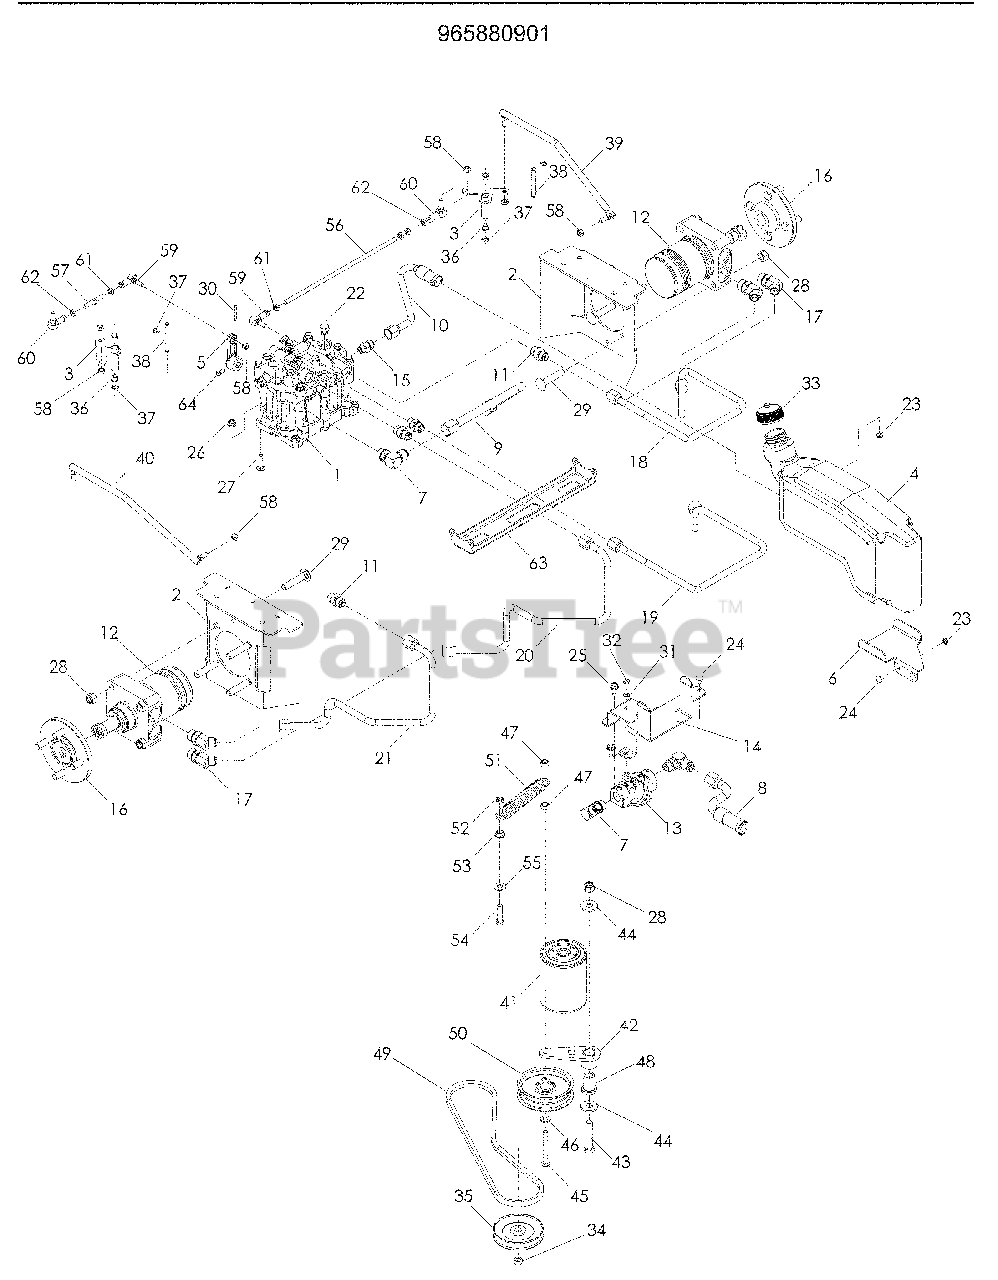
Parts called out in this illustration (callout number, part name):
1	PUMP, DUP10S
2	MOUNT, WHEEL MOTOR
3	BELLCRANK, MOTION
4	RESERVOIR, HYDRAULIC
6	SUPPORT, RESERVOIR FT
8	LINE, HYD, SUCTION
9	LINE, HYD, CHARGE
10	LINE, HYD, CASE
11	CONNECTOR, STRAIGHT
13	FILTER HEAD
14	SUPPORT, RESERVOIR RR
15	FITTING, HYD
16	HUB, WHEEL
17	ELBOW 45O
18	LINE, HYD, D
19	LINE, HYD, C
20	LINE, HYD, B
21	LINE, HYD, A
22	PLUG, 6408-6
23	NUT ¼-20 HEX THIN NYLOC
24	RHSSNB ¼-20 x ½
25	BOLT 5/16-18 x ¾ THD FRM
26	NUT 5/16-18 FLANGE NYLOC
27	RHSNB 5/16-18 x 1¼
28	NUT ½-13 HEX NYLOC
29	RHSNB ½-13 x 2½
30	PIN, SPIRAL 5/32 x 1½
31	WASHER ¼ SLW
32	HCS ¼-20 x 5/8
34	NUT, M10-1.5 L/H HEX
35	PULLEY, PUMP
36	BUSHING, BAIL 5/16
37	RING RETAINING 5/16 EXT
38	PIN, MOTION
39	LINKAGE, CONTROL LT
40	LINKAGE, CONTROL RT
41	FILTER, OIL
42	IDLER ARM WLDMT
43	HCS ½-13 x 2½
44	WASHER ½ FLAT
45	HCS 3/8-16 x 3 TAPBOLT
46	WASHER, 3/8 SAE FLAT
47	NUT 3/8-16 HEX NYLOC
48	PIVOT, IDLER
50	PULLEY, IDLER
51	SPRING, TRACTION
52	NUT 3/8-16 HEX JAM NYLOC
53	NUT 3/8-16 HEX WHIZLK
54	HCS 3/8-16 x 1½ TAPBOLT
55	WASHER 3/8 FLAT STD
56	LINKAGE, CONTROL, RR LT
57	LINKAGE, CONTROL, RR RT
58	NUT 5/16-24 TOP LK
59	SPHERICAL ROD END RH
60	SPHERICAL ROD END LH
61	NUT 5/16-24 HEX JAM LH
62	NUT 5/16-24 HEX JAM
63	SUPPORT, WHEEL MOTOR
64	SCREW 5/16-18 x 5/8 SET
